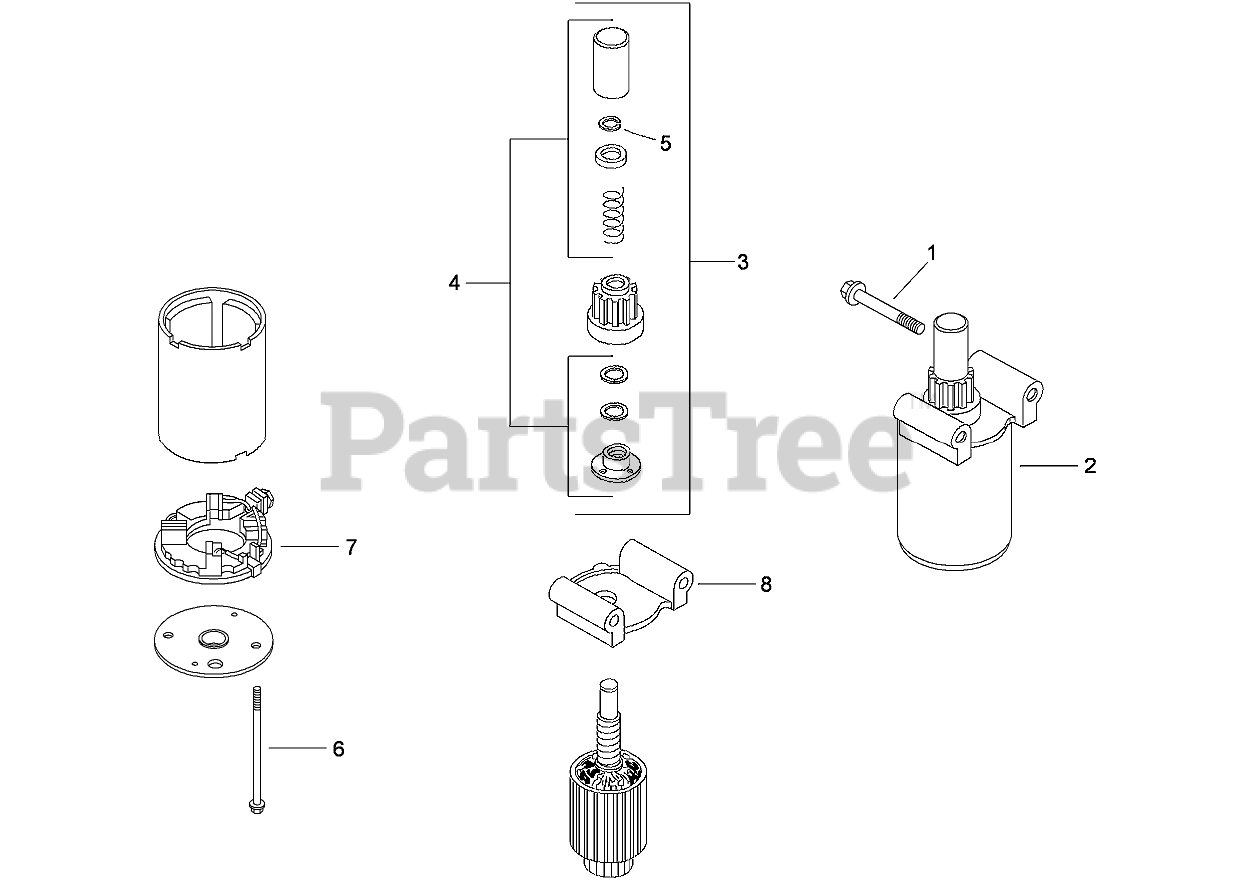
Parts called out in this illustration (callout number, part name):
1	SCREW-FLG (M8X1.25X80)
2	STARTER ASM
3	DRIVE KIT
4	DRIVE PART KIT
5	RING-RETAINING
6	BOLT-THRU
7	COMMUTATOR-CAP, END
8	CAP-END, DRIVE
